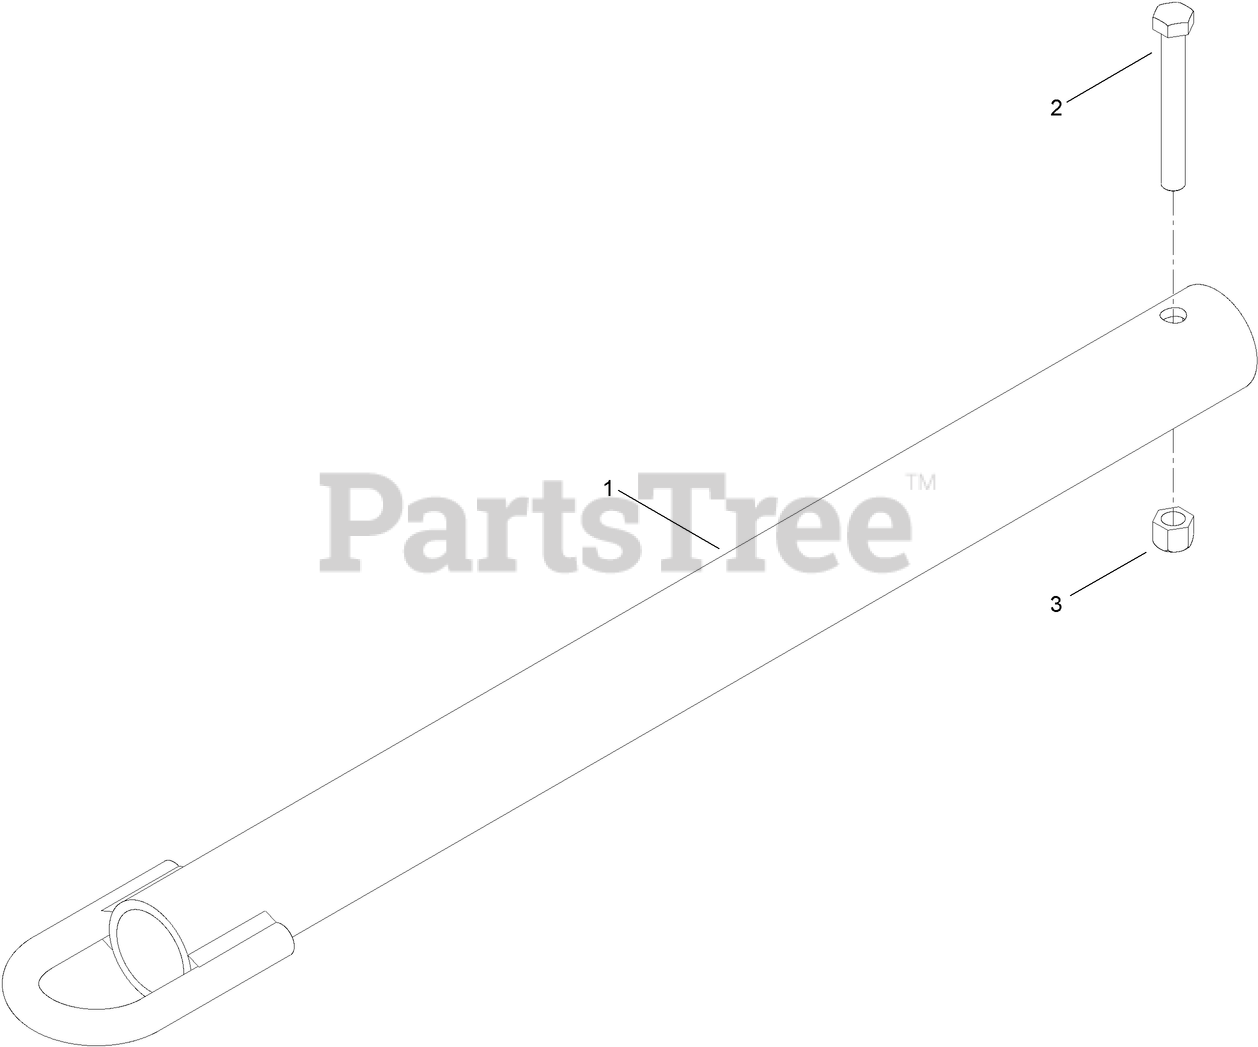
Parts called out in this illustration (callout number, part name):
1	POLE-TOW, 31 INCH (PINTEL)
2	SCREW-HH
3	NUT-LOCK, NI
